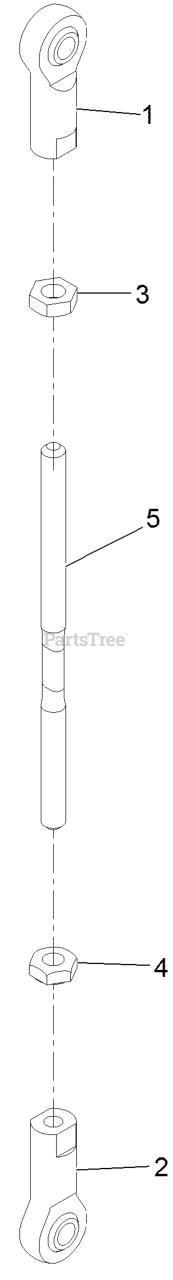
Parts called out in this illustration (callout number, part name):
1	ROD END-BALL JOINT
2	JOINT-BALL, LH
3	NUT-JAM
4	NUT-JAM
